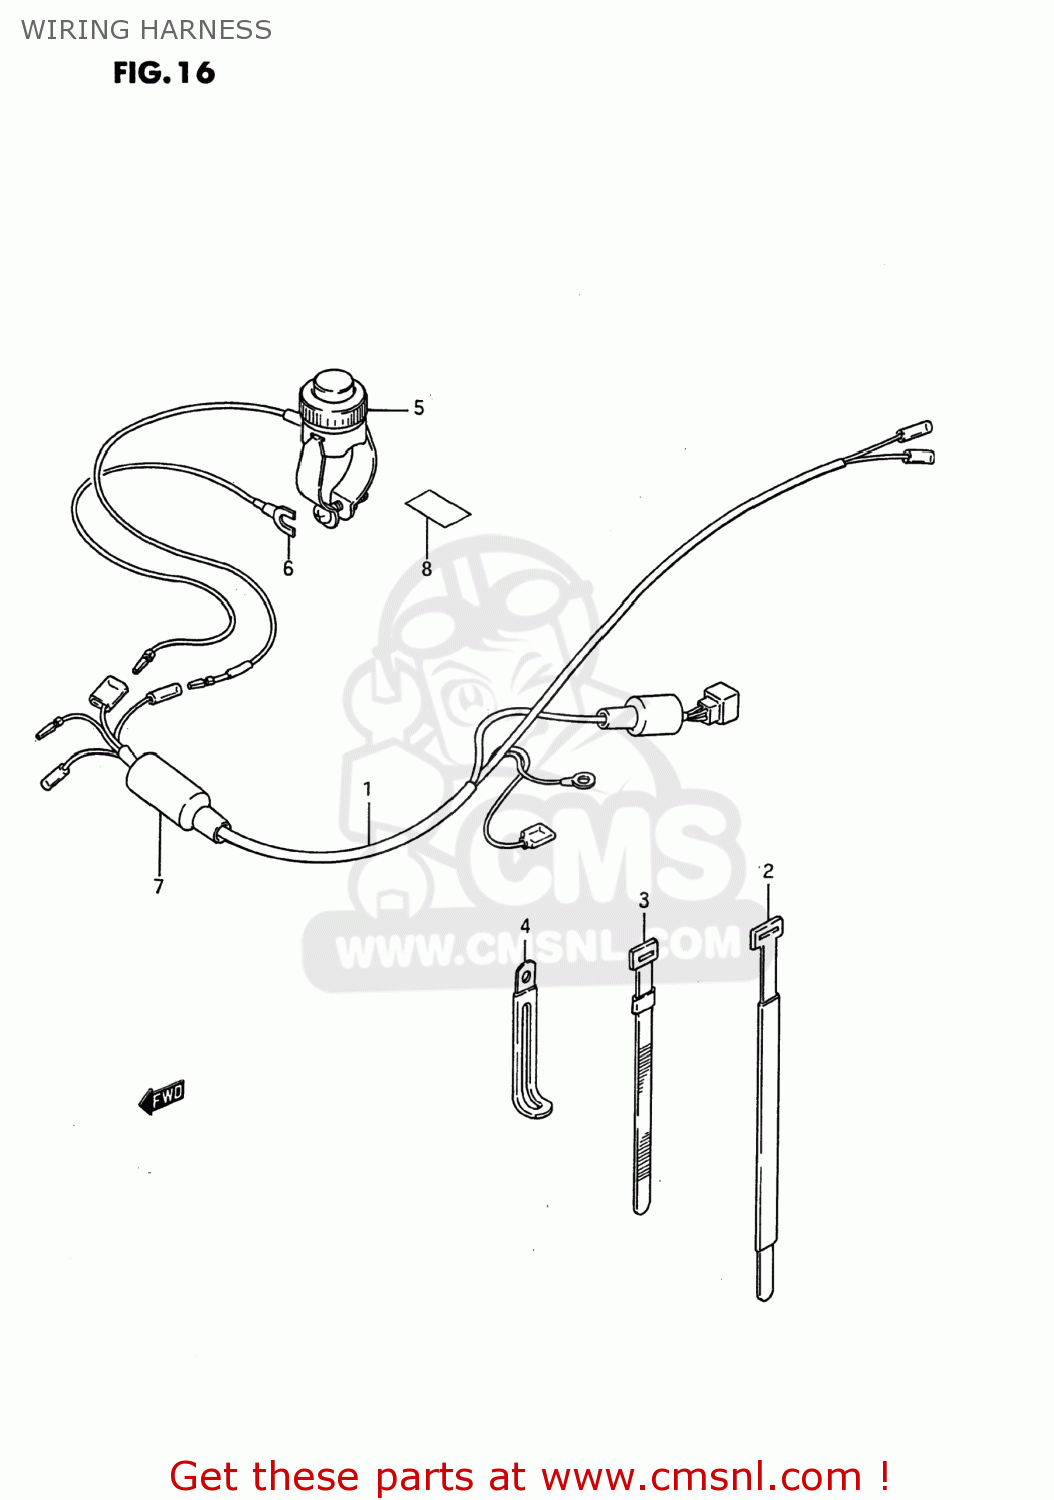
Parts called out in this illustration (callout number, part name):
1	HARNESS,WIRING
2	CLAMP
3	CLAMP(L:120)
4	CLAMP(L:45)
5	SWITCH ASSEMBLY
6	WIRE,LEAD
7	COVER,WIRE
8	LABEL (ENGINE STOP)
